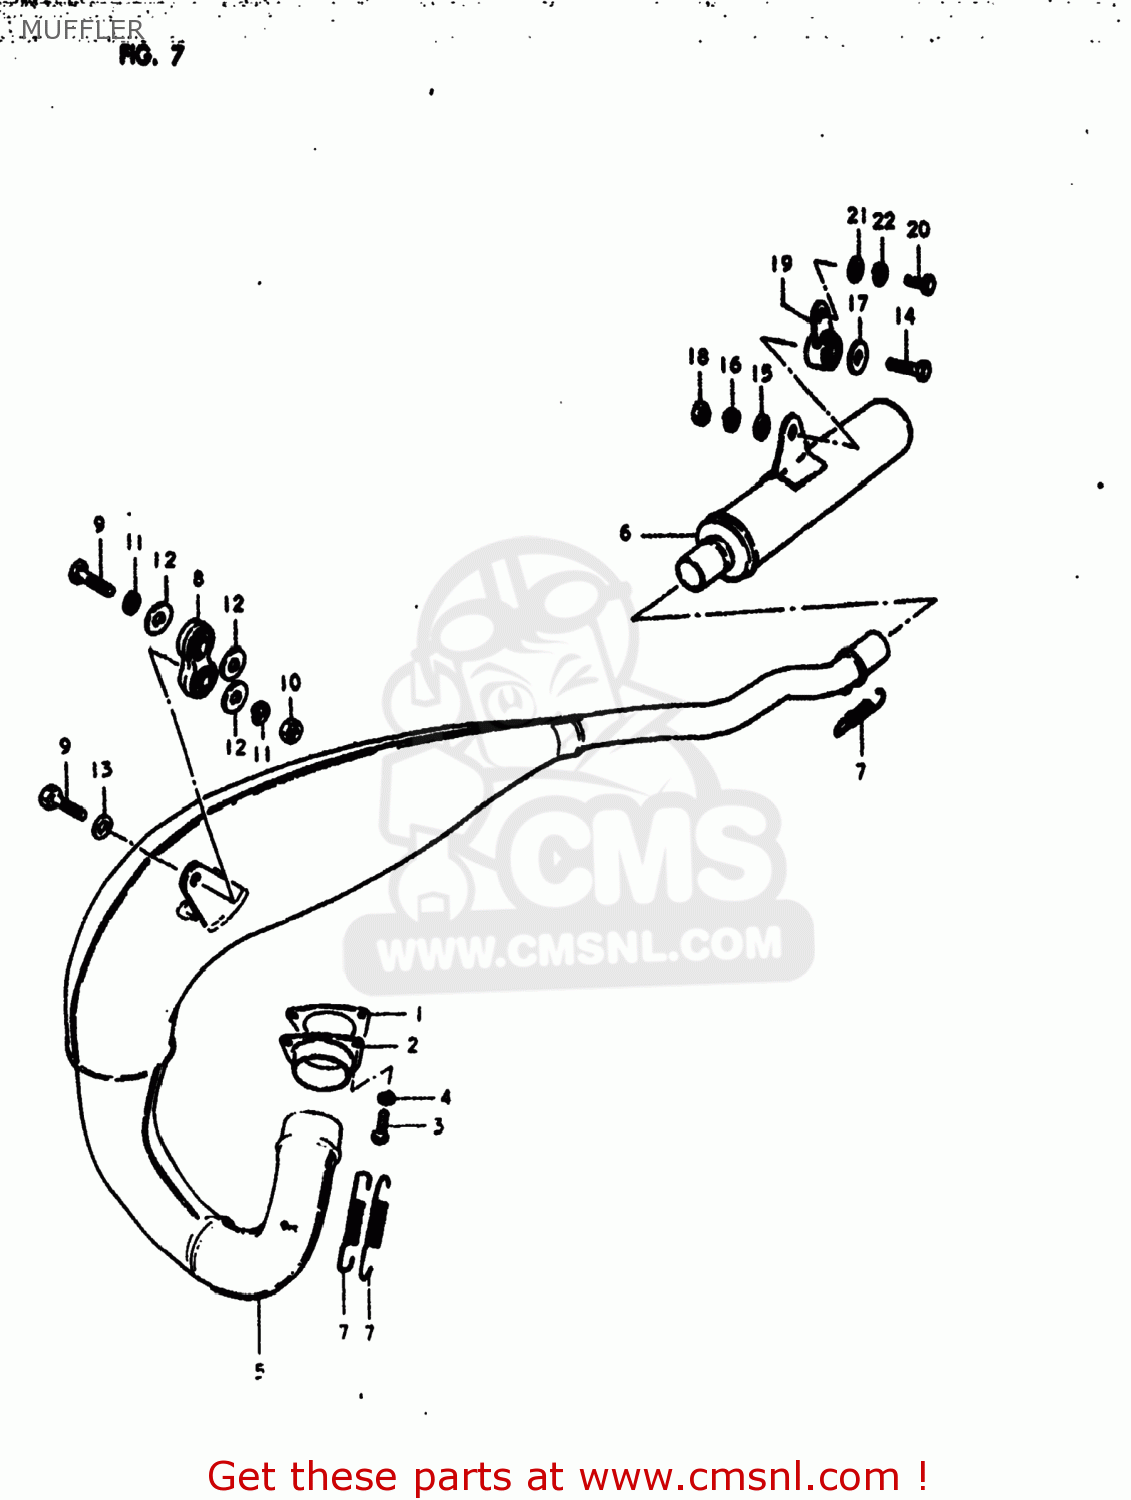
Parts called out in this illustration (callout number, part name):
1	GASKET,EXHAUST PIPE (MCA)
2	FLANGE,EXHAUST PIPE
3	SCREW
4	LOCK WASHER
5	BODY,MUFFLER
6	BODY,MUFFLER
7	SPRING
8	DAMPER,MUFFLER
9	BOLT
10	NUT
11	LOCK WASHER
12	WASHER
13	WASHER
14	BOLT (8X30)
15	WASHER
16	LOCK WASHER
17	WASHER (8.5X29X1.6)
18	NUT
19	DAMPER,MUFFLER SUPPORT
20	BOLT
21	WASHER
22	LOCK WASHER
